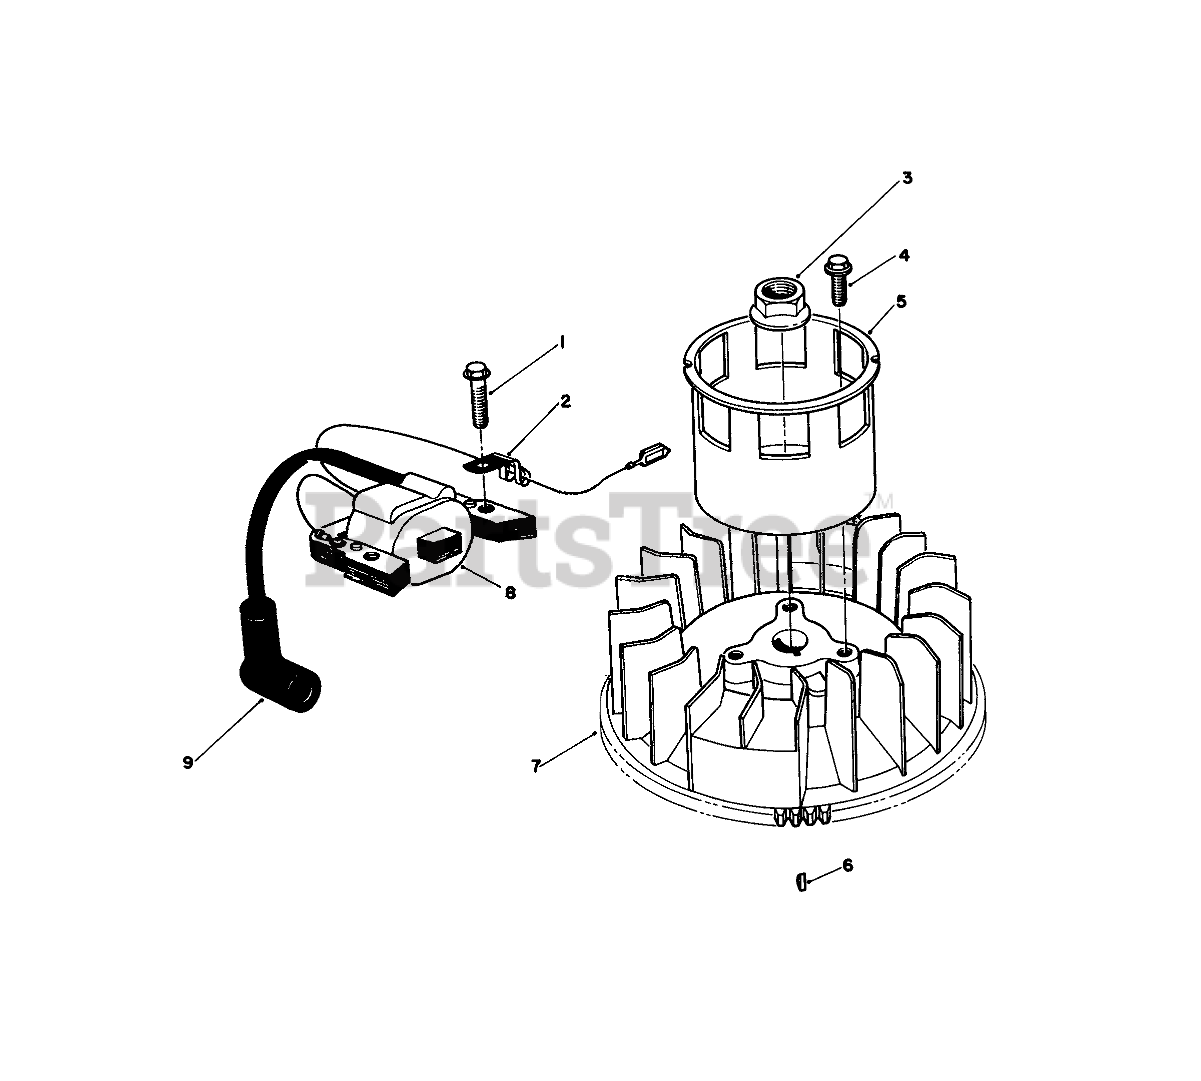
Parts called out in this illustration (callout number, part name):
2	CLAMP
7	FLYWHEEL
8	COIL
9	COVER
